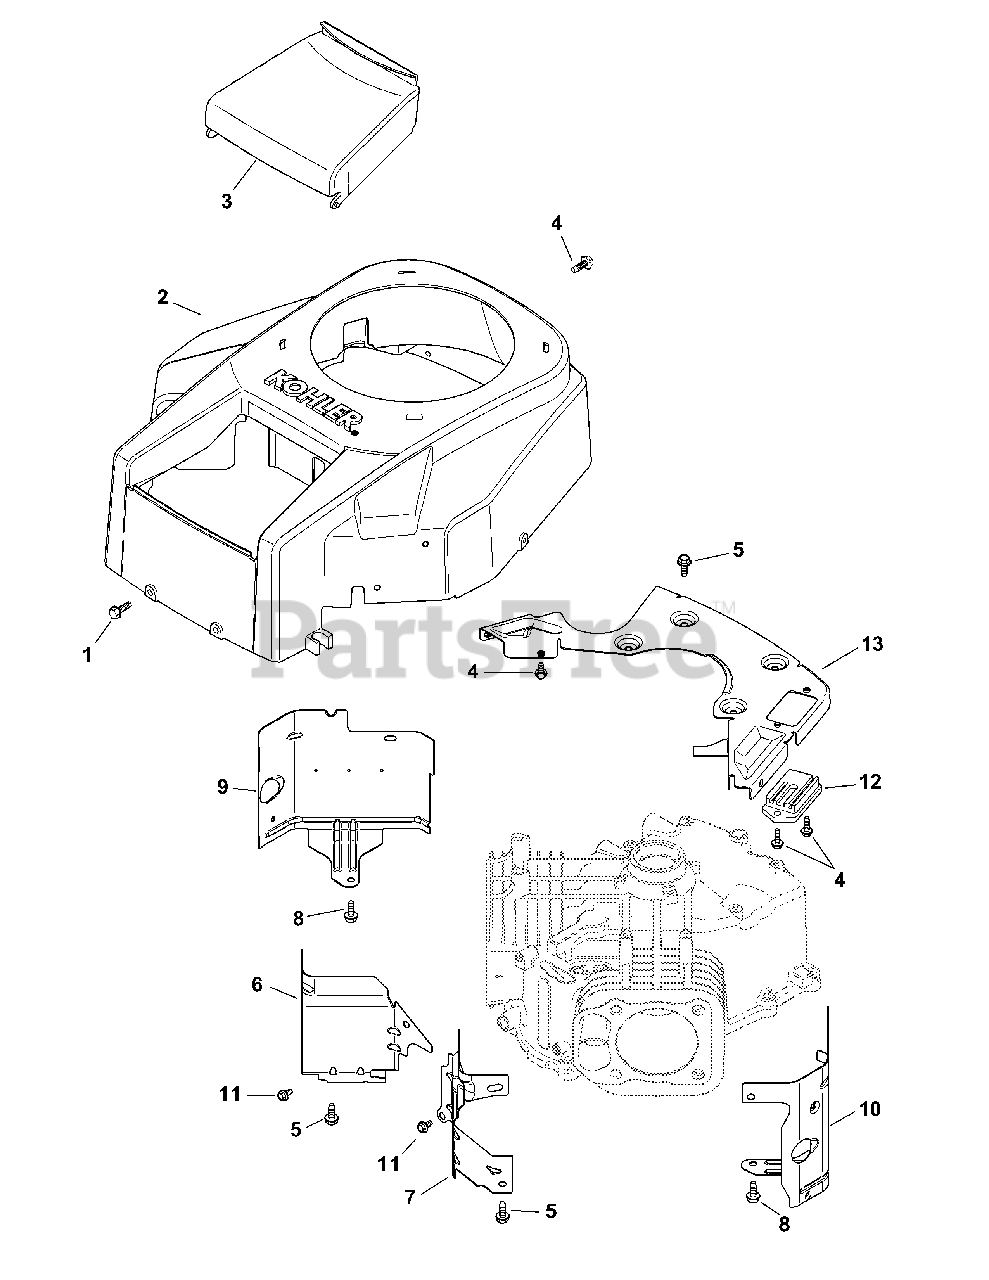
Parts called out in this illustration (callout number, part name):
1	Tap Screw, M6 x 1.7 x 18
2	Housing Blower Kit
3	Air Cleaner Cover
4	Flg. Thd. Frm. Screw, M5 x 0.8 x 16
5	Flg. Thd. Frm. Screw, M6 x 1.0 x 16
6	Valley Baffle - #1 Cylinder
7	Valley Baffle - #2 Cylinder
8	Flng. Thd. Frm. Screw, M6 x 1.0 x 10
9	Cyl Barrel Baffle - #1 Side
10	Cyl Barrel Baffle - #2 Side
11	Flg. Thd. Frm. Screw, M5 x .8 x 10
12	Regulator/Rectifier
13	Backing Plate Kit
